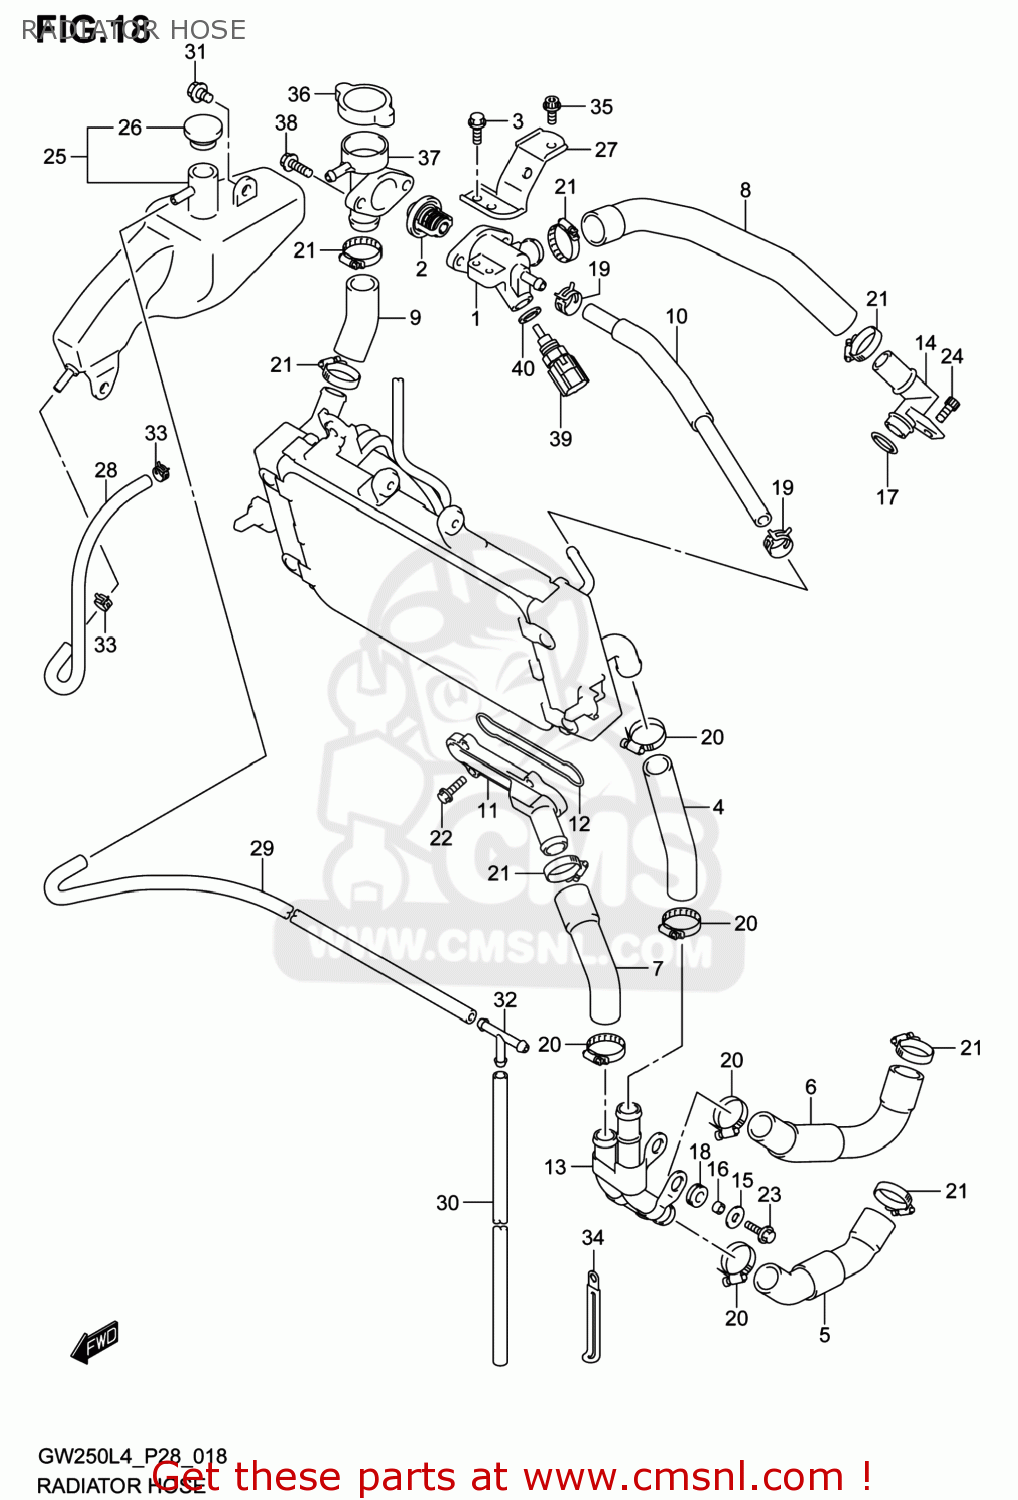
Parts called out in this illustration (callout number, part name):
1	CONNECTOR,THERMOSTAT INLET
2	THERMOSTAT,WATER
3	BOLT
4	HOSE,RADIATOR OUTLET
5	HOSE,WATER PUMP INLET
6	HOSE,WATER PUMP OUTLET
7	HOSE,CYLINDER CONNECTOR
8	HOSE,THERMOSTAT CONNECTOR
9	HOSE,RADIATOR INLET
10	HOSE,WATER BYPASS
11	CONNECTOR,CYLINDER WATER INLET
12	O RING,CYL INLET CONNECTOR
13	PIPE,WATER PUMP
14	PIPE,CYLINDER HEAD OUTLET
15	WASHER(6.5X18X1)
16	SPACER(6.5X9X5)
17	O RING(D:3.2,ID:17.8)
18	CUSHION
19	CLIP
20	CLAMP
21	CLAMP
22	BOLT
23	BOLT
24	BOLT
25	TANK ASSY,RESERVOIR
26	CAP,RESERVOIR TANK
27	BRACKET,RESERVOIR TANK
28	HOSE,RESERVOIR TANK INLET
29	HOSE SET,RESERVOIR TANK INLET
30	HOSE,FUEL TANK WATER DRAIN
31	BOLT(6X12)
32	3 WAY
33	CLIP
34	CLAMP
35	BOLT
36	CAP,RADIATOR(1.1)
37	CONDUCTION,RADIATOR
38	BOLT
39	SENSOR,TEMP
40	GASKET,TEMP SENSOR (NAS)
